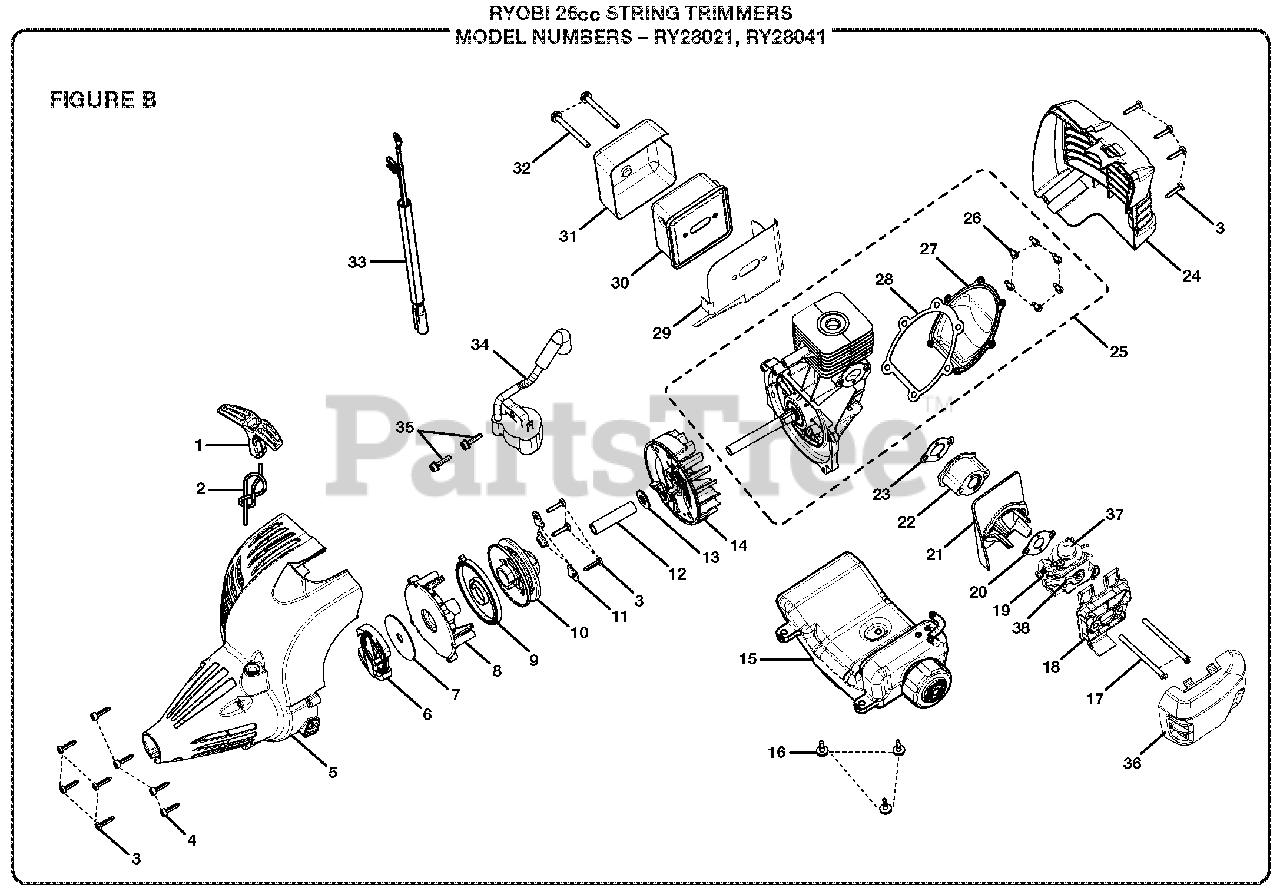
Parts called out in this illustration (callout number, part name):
1	Starter Grip
2	Starter Rope
3	Screw (M4 x 18 mm)
4	Screw (M4 x 16 mm)
5	Starter Housing Assembly
6	Clutch Assembly
8	Starter Baffle
9	Spring and Container
10	Easy Starter Assembly
11	Pulley Retainer
12	Spacer Tube
13	Washer
14	Flywheel Assembly
15	Fuel Tank and Cap Assembly
16	Screw (M4)
17	Bolt (M5 x 70 mm)
18	Air Box Base
19	Carburetor Assembly
20	Outer Heat Dam Gasket
21	Air Baffle
23	Inner Heat Dam Gasket
24	Rear Housing
25	Short Block Assembly
26	Screw (M4 x 12 mm)
27	Crankcase Cover
28	Crankcase Cover Gasket
29	Muffler Gasket
30	Muffler Assembly
31	Muffler Housing
32	Muffler Bolt (10-24 x 2-1/8 in.)
33	Electrical Lead Wire Assembly
34	Ignition Module
35	Screw (M4 x 19 mm)
36	Air Box Cover
37	Primer Bulb
38	Choke Lever
